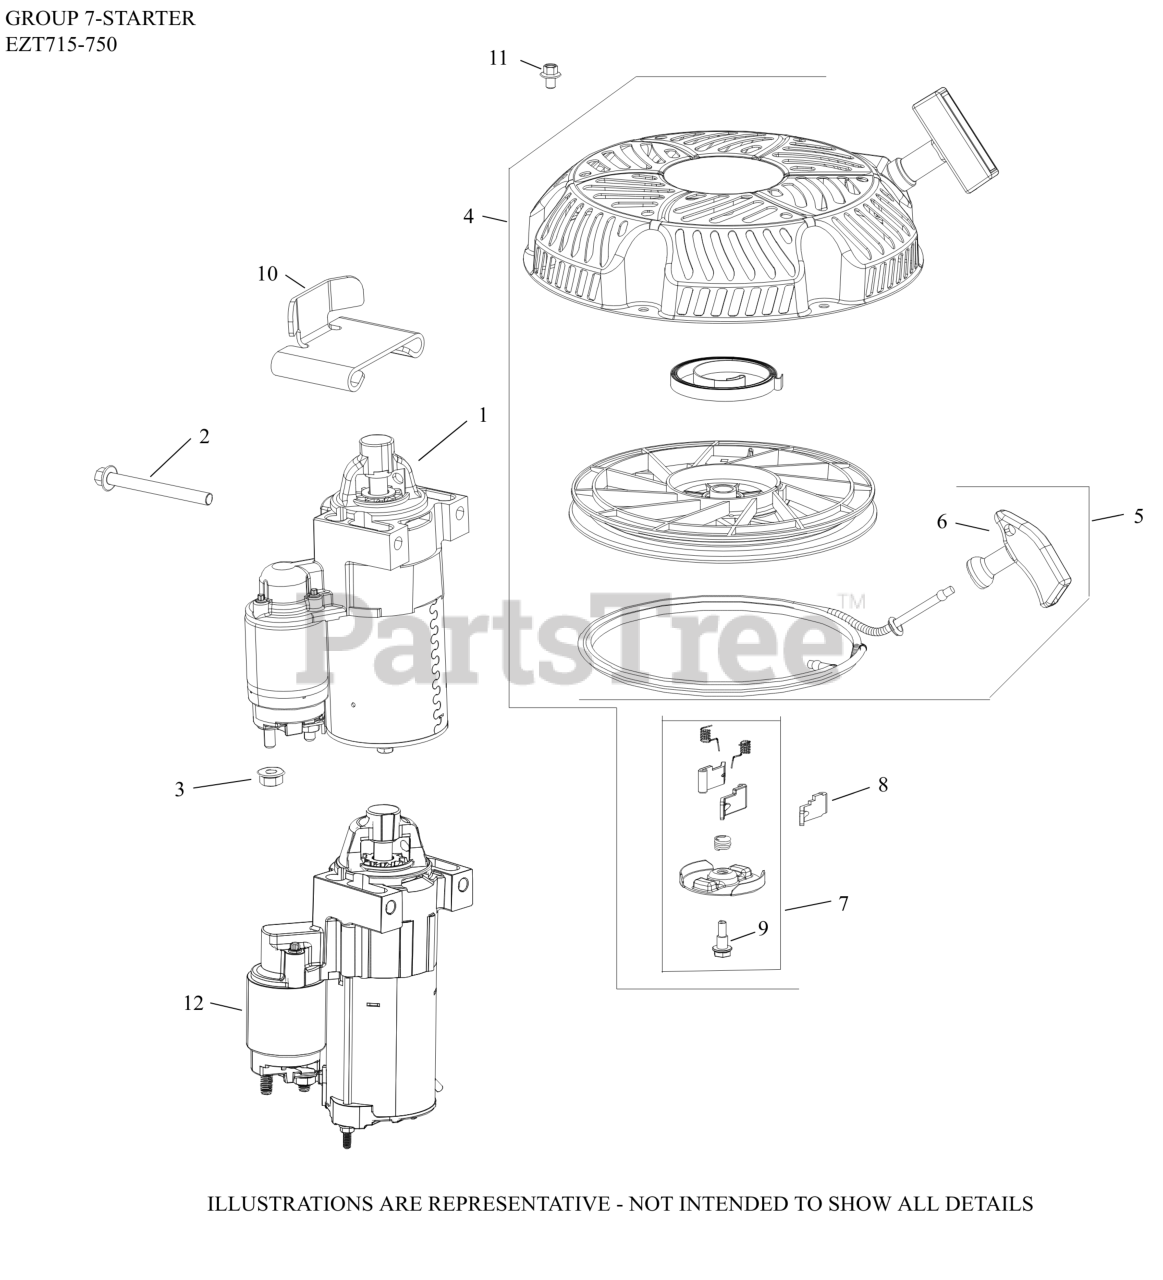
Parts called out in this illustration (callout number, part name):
1	STARTER, SOLENOID SHIFT-(#2509824S)
2	SCREW, FLG M8X1.25X80
3	NUT, FLG M8X1.25
